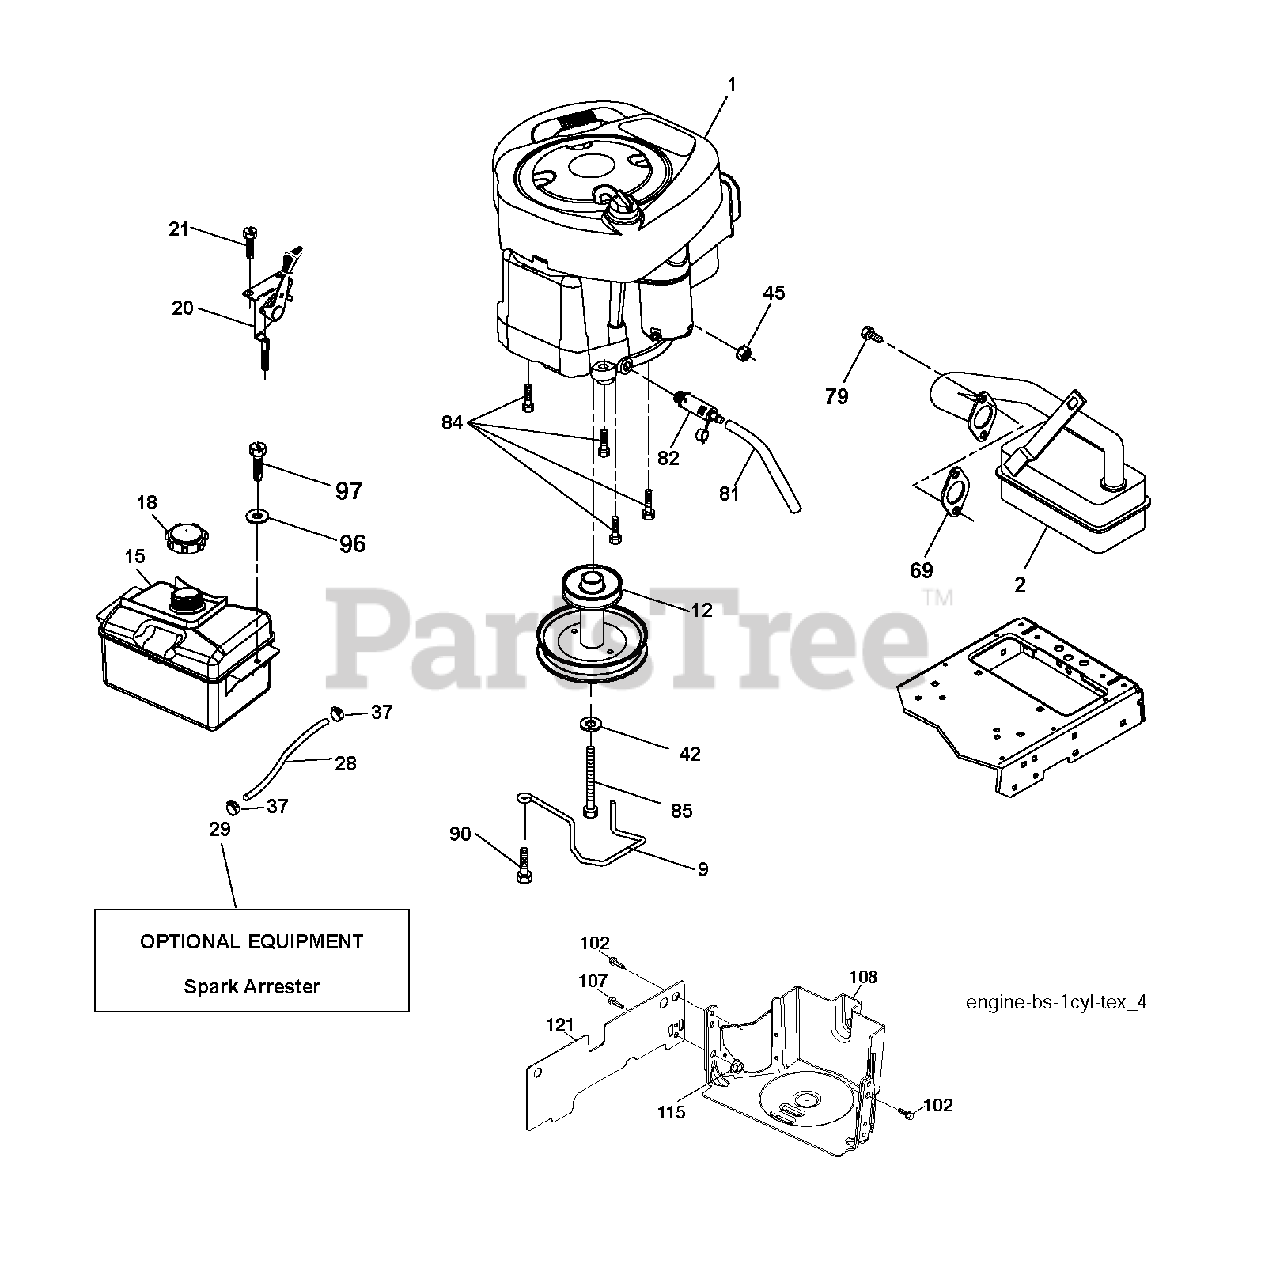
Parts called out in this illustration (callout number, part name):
9	KEEPER.BELT.ENGINE.3.25
12	PULLEY ENGINE
15	TANK FUEL FRT 1.5 GAL
18	FUEL CAP
20	CONTROL.TH/CK.C.
21	SCREW.#10 X 0.750.BOS THREAD
28	LINE.FUEL.20
29	ARRESTER SPARK (OPTIONAL)
37	HOSE CLAMP
42	LOCKWASHER
45	NUT
69	REPL BY 532 27 22-93
79	SCREW.SOCKET HD.5/16-1
81	TUBE, DRAIN OIL ASM.
82	PLUG DRAIN OIL EASY
84	SCREW.3/8-16
85	BOLT HEX 7/16-20X4-1/4"
90	SCREW 3/8-16X1
97	SCREW HEXWSHR 1/4-20X3/4
102	SCREW
107	SCREW.1/4-20X5/8
115	PALNUT 1/4
